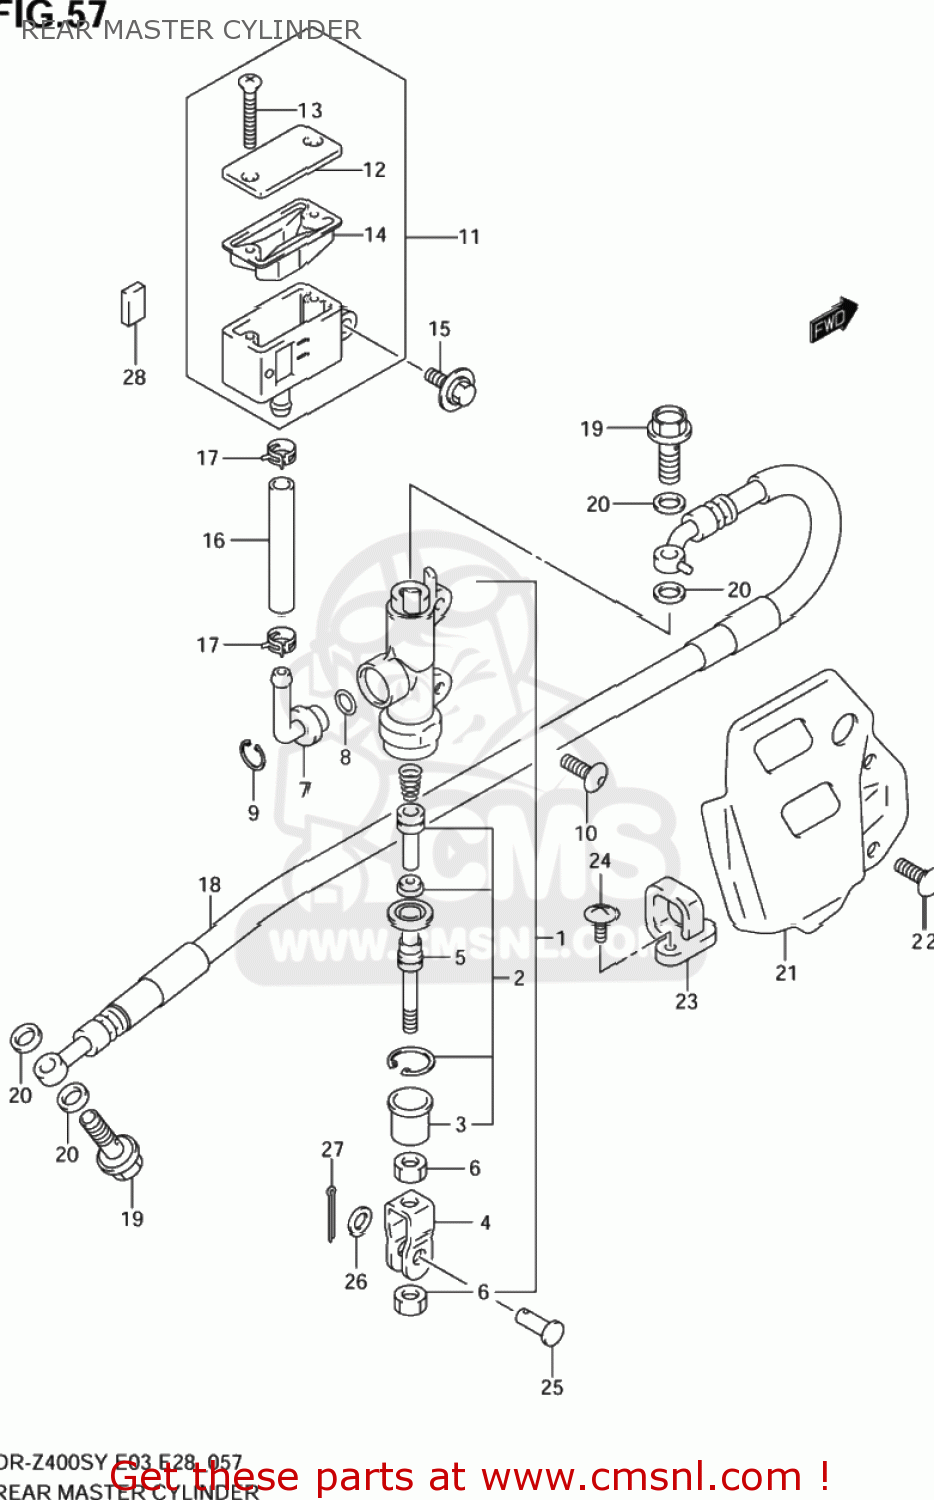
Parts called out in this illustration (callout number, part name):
1	CYLINDER ASSY,RR MASTER
2	PISTON/CUP SET
3	BOOT
4	YOKE
5	ROD,PUSH
6	NUT
7	CONNECTOR
8	O RING
9	CIRCLIP
10	SCREW(6X16)
11	TANK ASSY,RESERVOIR
12	CAP
13	SCREW
14	DIAPHRAGM
15	BOLT(6X16)
16	HOSE,FR RESERVOIR TANK
17	CLAMP,RESERVOIR HOSE
18	HOSE COMP,REAR BRAKE
19	BOLT UNION
20	WASHER(10X15X1.5)
21	GUARD,RR MASTER CYLINDER
22	SCREW(6X16)
23	GUIDE,RR BRAKE
24	SCREW
25	PIN(8X20)
26	WASHER (8.5X14X1.6)
27	PIN
28	CUSHION,RR RESERVOIR TANK
